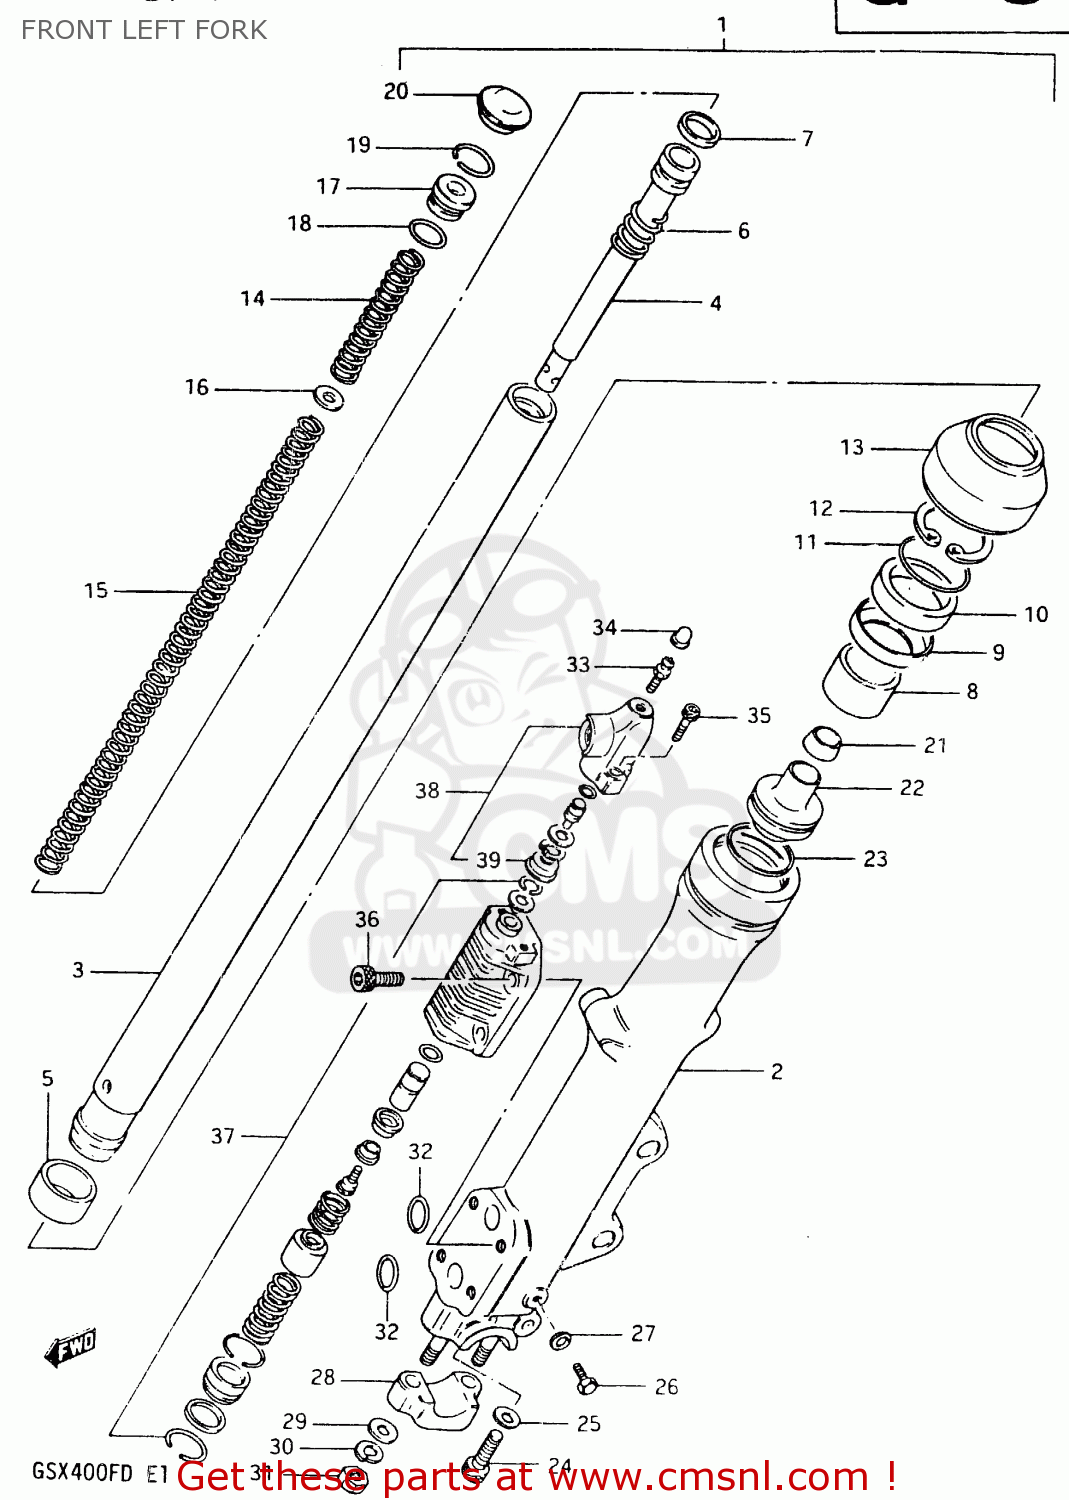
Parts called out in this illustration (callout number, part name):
1	FRONT LH DAMPER
2	OUTER TUBE LH
3	INNER TUBE
4	CYLINDER, LH
5	BUSH
6	SPRING,REBOUND
7	RING,PISTON
8	BUSH,GUIDE
9	SPACER,OIL SEAL
10	OIL SEAL,FRONT FORK
11	RING,BACKUP
12	RING,OIL SEAL STOPPER
13	DUST SEAL
14	SPRING A
15	SPRING (B)
16	SEAT,SPRING
17	SEAT,SPRING
18	O RING
19	RING,STOPPER
20	CAP
21	VALVE,OIL LOCK PIEACE
22	PIECE,OIL LOCK
23	RING, PISTON
24	BOLT(8X27)
25	GASKET (NAS)
26	BOLT
27	GASKET,DRAIN,PLUG (NAS)
28	HOLDER,AXLE
29	WASHER
30	LOCK WASHER
31	NUT
32	O RING,FR FORK
33	BREATHER
34	CAP
35	BOLT
36	BOLT
37	MODULATOR VALVE SET
38	MODULATOR PARTS SET,FRONT
39	SEPARATOR,FRONT FORK MODULATOR
